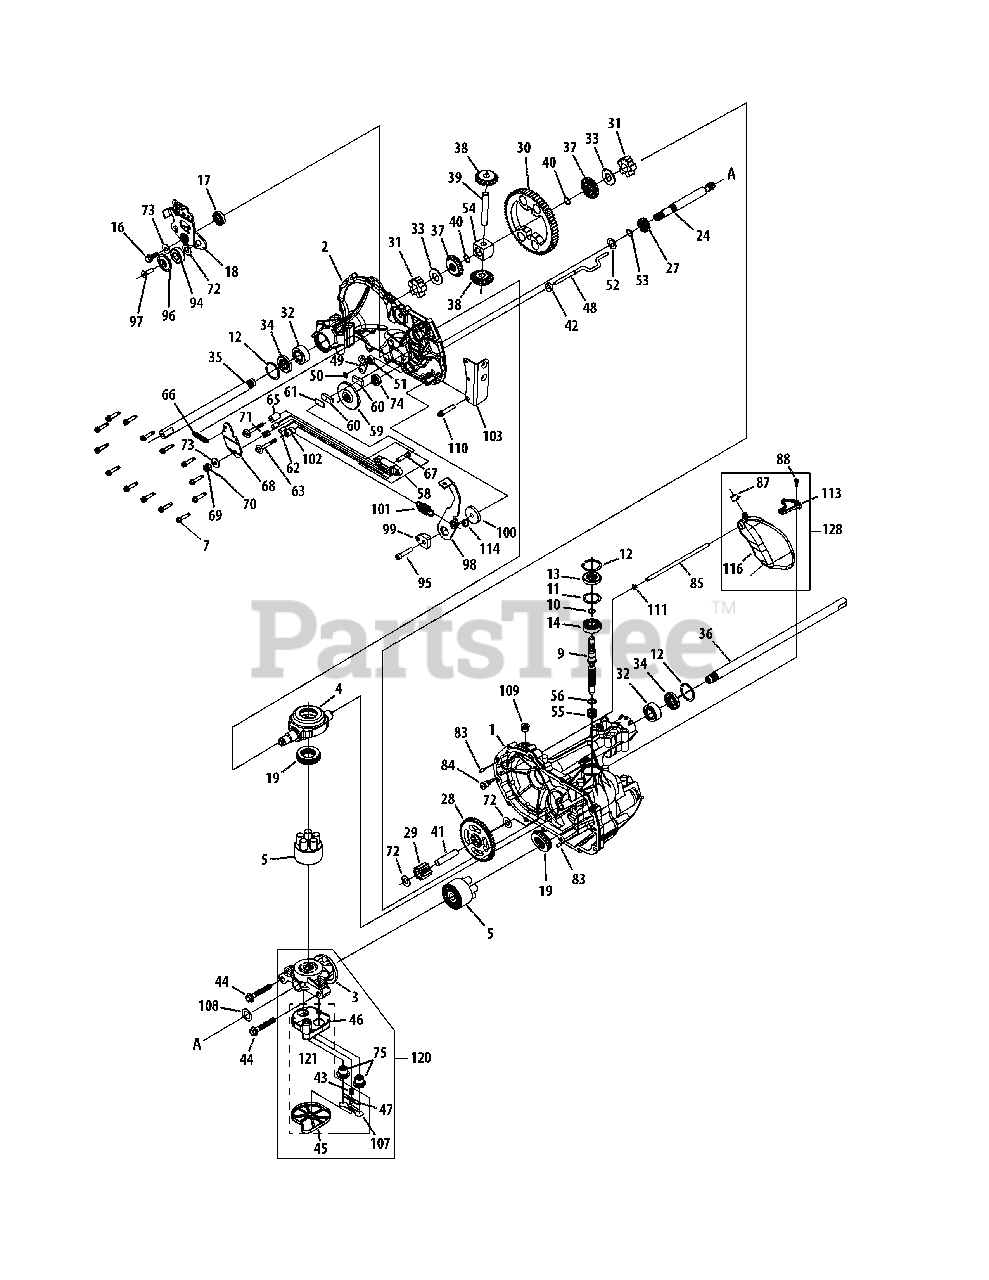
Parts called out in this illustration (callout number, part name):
1	Main Housing Assembly
1	Main Housing, Machined
1	Bushing ,865 x 985 x .790
2	Main Housing Assembly
2	Main Housing, Machined
2	Bushing ,865 x 985 x .790
2	Bushing 624 x 719 x . 562
3	Center Section Assembly
3	Center Section Machined
3	Bushing. 707 x . 788 x . 591
4	Swashplate, Trunnion Machined
5	Block - Assembly
5	Block - Cylinder
5	Piston
5	Spring, Compression
5	Washer - Thrust
7	Hex Flange Screw 1/4-20 x-1,25
9	Shaft, Input
10	Ring - Retaining
12	Ring - Retaining
13	SeaL Lip .67 x 1.58 x .276
14	Ball Bearing 17mm Id x 40mm Od
16	Bolt. Flange 5/16-24 x .94 (Patch)
17	Lip Seal 18 x 32 x 7
18	Arm Control
19	Bearing 30x52 x 13 Thrust
24	Shaft Motor
27	Gear - Pinnion 12t
28	10t/49t Gear
29	Gear Jot Jackshaft
30	60t Bull Gear
31	Sleeve Bearing . 75 x 1.750 x .625
32	Sleeve Bearing .75 x 1.575 x ,625
33	Washer 3/4 Id x 1-1/2 Od x .13 Thk
34	Lip Seal Axle Seal
35	Shaft Axle . 75 x 11. 39 ( Dd R. H, )
36	Shaft Axle .75 x 17. 99 ( Dd, L, H.)
37	Miter Gear (Splined)
38	Miter Gear 15t (0 .5 Id)
40	Ring, Spiral Retaining
41	Pin, Jackshaft
42	Magnet, Ring
43	Spring, Bypass
44	Hydro Mtg Screw 3/8-24 x 2.5
45	Bottom, Filter
46	Base Filter W/ Poppet
47	Actuator Bypass
48	Rod Bypass Actuator
49	Arm, Bypass
50	Retaining Ring 0.250 External
51	Seal, Lip . 741 x .250 x .250 Tc
52	Flat Washer 5/8 Id x 1.0 Od x . 05
53	Retaining Ring
54	Bearing, Center Block
55	Spring - Helical Compression
58	Kit, Brake Yoke
58	Brake Yoke
58	Sq. Hd, Bolt 5/16-24 Ribbed
59	Rotor, Brake
60	Brake Puck
61	Puck Plate
62	Brake Actuating Pin
63	Hex Screw 1/4-20 x 2 w/ Patch
66	Kit, Spring
67	So. Hd, Bolt 5/16-24- Ribbed
68	Arm, Brake
69	Slotted Hex Nut 5/16-24
70	Cotter Pin 3/32 x 3/4
71	Comp. Spring Brake Anti-Drag
72	Washer, Ht .5 I. D. x 1 OD, x .032
73	Flat Washer, 11/32 ID x 7/8 OD
74	Kit, Seal
74	Oil, Seal 625 x Lo x .25
74	Ring, Ret-Star Washer
74	Bulletin, Shaft Seal
75	Check Plug Assem, .027 Washer
83	Pin, Standard Headless
84	Fitting, 5/16 Sae 5/32 Tube
85	Hose, Expansion Tank
87	Cap,. Vent
88	Bolt, Self Tapping 10-32 x 112
94	Ball Bearing .62 Id x 1,38 x 44
95	Cap Screw, 5/16-24 x 1-112
96	Spacer, Locating
97	Screw, Sfhcs
98	Arm, Return
99	Puck, Adjusting
100	Washer, .32 OD x 1.6 ID x .24
101	Spring, Extension
102	Spacer, .56 x .26 x .87
103	Bracket, Torque
107	Deflector
108	Washer, Motor Shaft .71 Id 1.15 Od
110	Torx Head Screw, 5/16-18
111	O-Ring, .07 x .301 ID
113	Bracket, Support Expansion Tank
114	Spring Guide
116	Silicon Sponge
120	Center Section - Bypass Assm
120	Center Section Machined
120	Base Filter w/ Poppet
120	Check Plug Assembly
120	Spring Bypass
120	Actuator Bypass
120	Deflector
120	Bottom, Filter
120	Bushing, .707 x .788 x .591
121	Filter Assembly
121	Bottom Filter
121	Base Filter w/ Poppet
121	Spring Bypass
121	Actuator Bypass
121	Deflector
128	Kit, Expansion Tank
128	Tank, Expansion
128	Cap, Vent
128	Bolt, Self Tapping 10-32 x 1/2
128	Bracket, Support Expansion Tank
128	Silicon-Sponge 112 x 1/2 x 3/16
